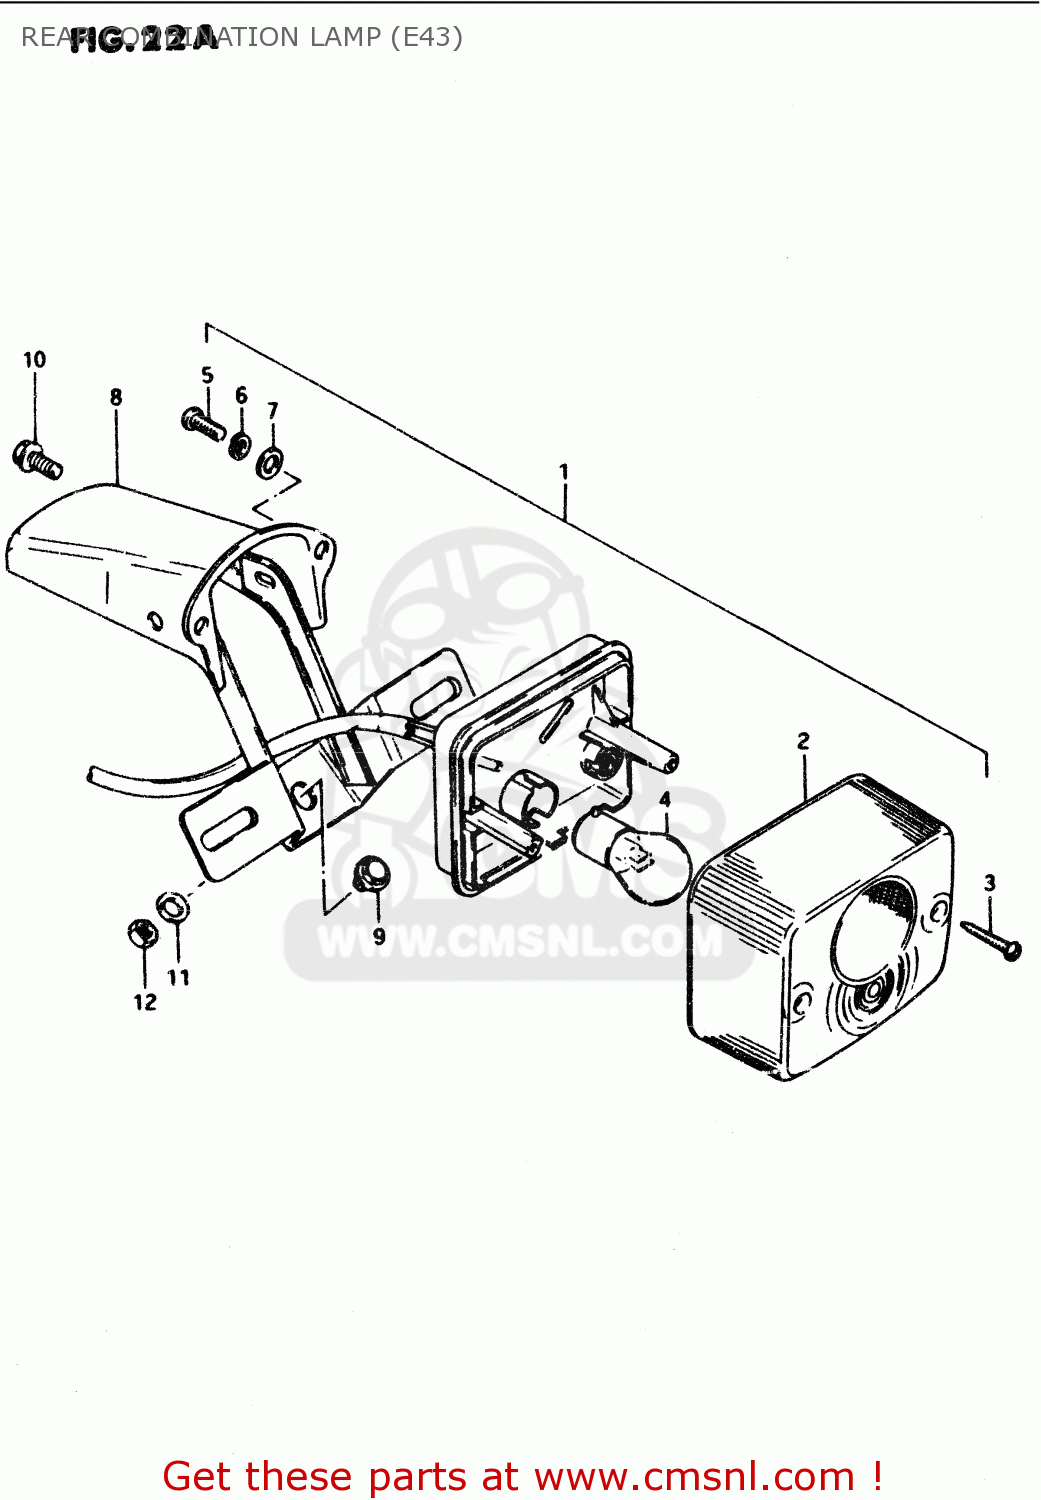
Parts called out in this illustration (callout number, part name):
1	LAMP UNIT, REAR COMBINATION
2	LENS
3	SCREW
4	BULB(6V10/3W,STANLEY,A4854H)
5	SCREW
6	WASHER,LOCK
7	WASHER,5MM
8	BRACKET
9	BOLT
10	BOLT
11	WASHER, LOWER
12	NUT
